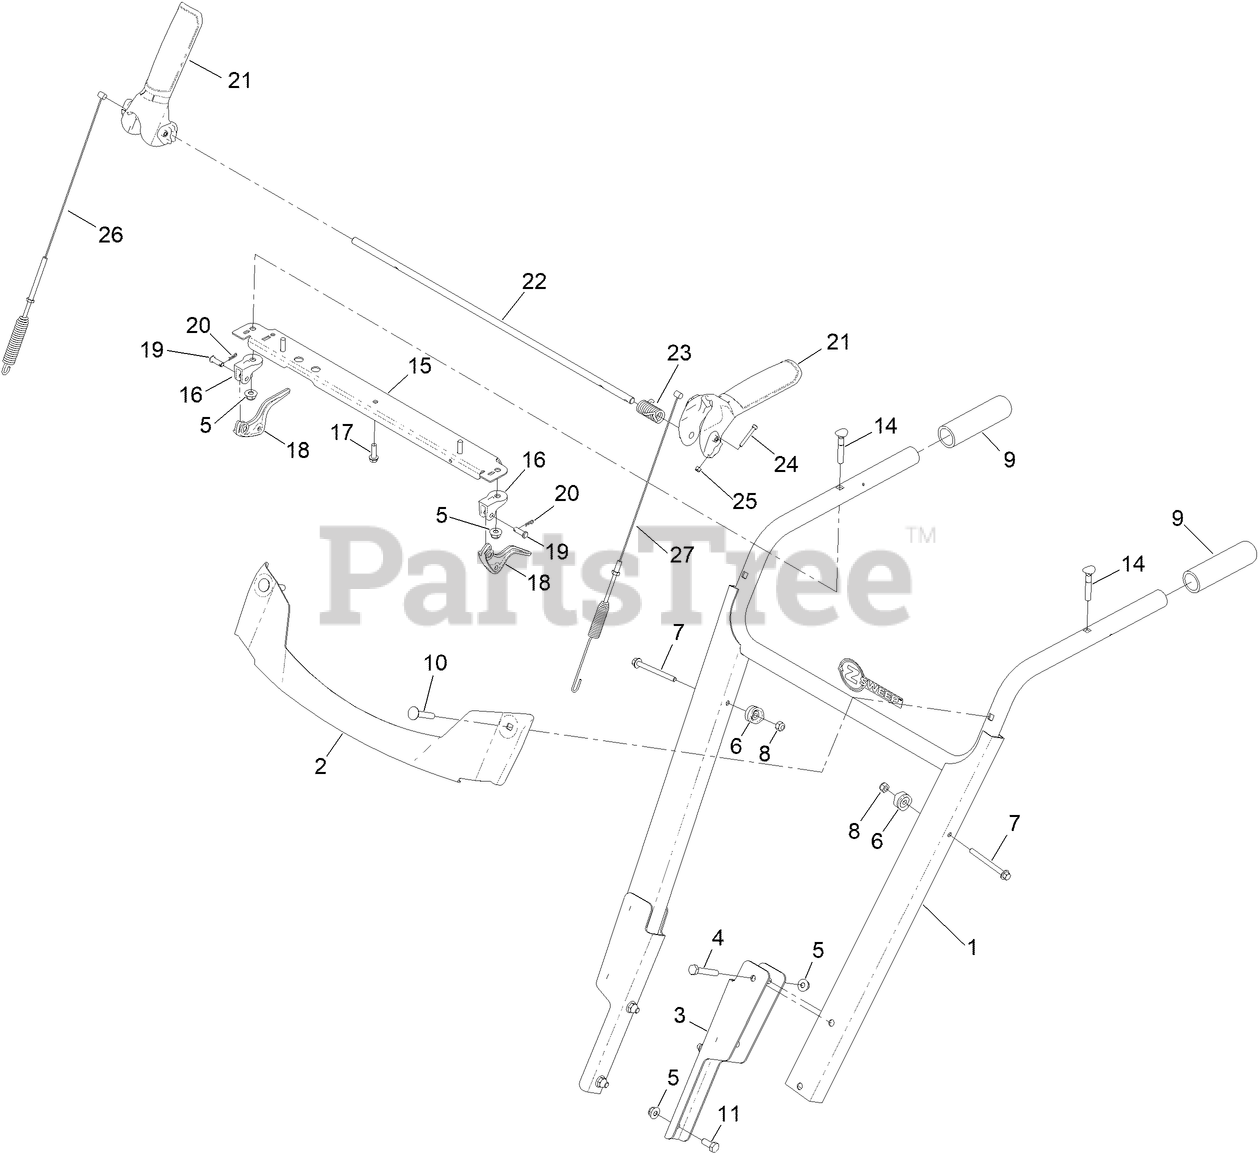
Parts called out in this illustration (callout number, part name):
1	HD HANDLE ASM
2	TRIM-METAL, HD
3	BRACKET-HANDLE, LOWER
4	SCREW-HH
5	NUT-HF
6	CLAMP-CABLE
7	SCREW-HHF
8	NUT-HEX
9	GRIP-HANDLE
10	BOLT-CARR
11	SCREW-HH
14	SCREW-HANDLE
15	BRACE-CONSOLE
16	MOUNT-LEVER, CLUTCH
17	SCREW-PLASTITE, HWH
18	LEVER-CLUTCH
19	PIN-CLEVIS
20	PIN-HAIR
21	LEVER-CONTROL
22	ROD-LOCKOUT
23	SPRING-TORSION, HANDLE RETURN
24	SCREW-HSH
25	NUT-LOCK
26	CABLE-AUGER
27	CABLE-TRACTION
